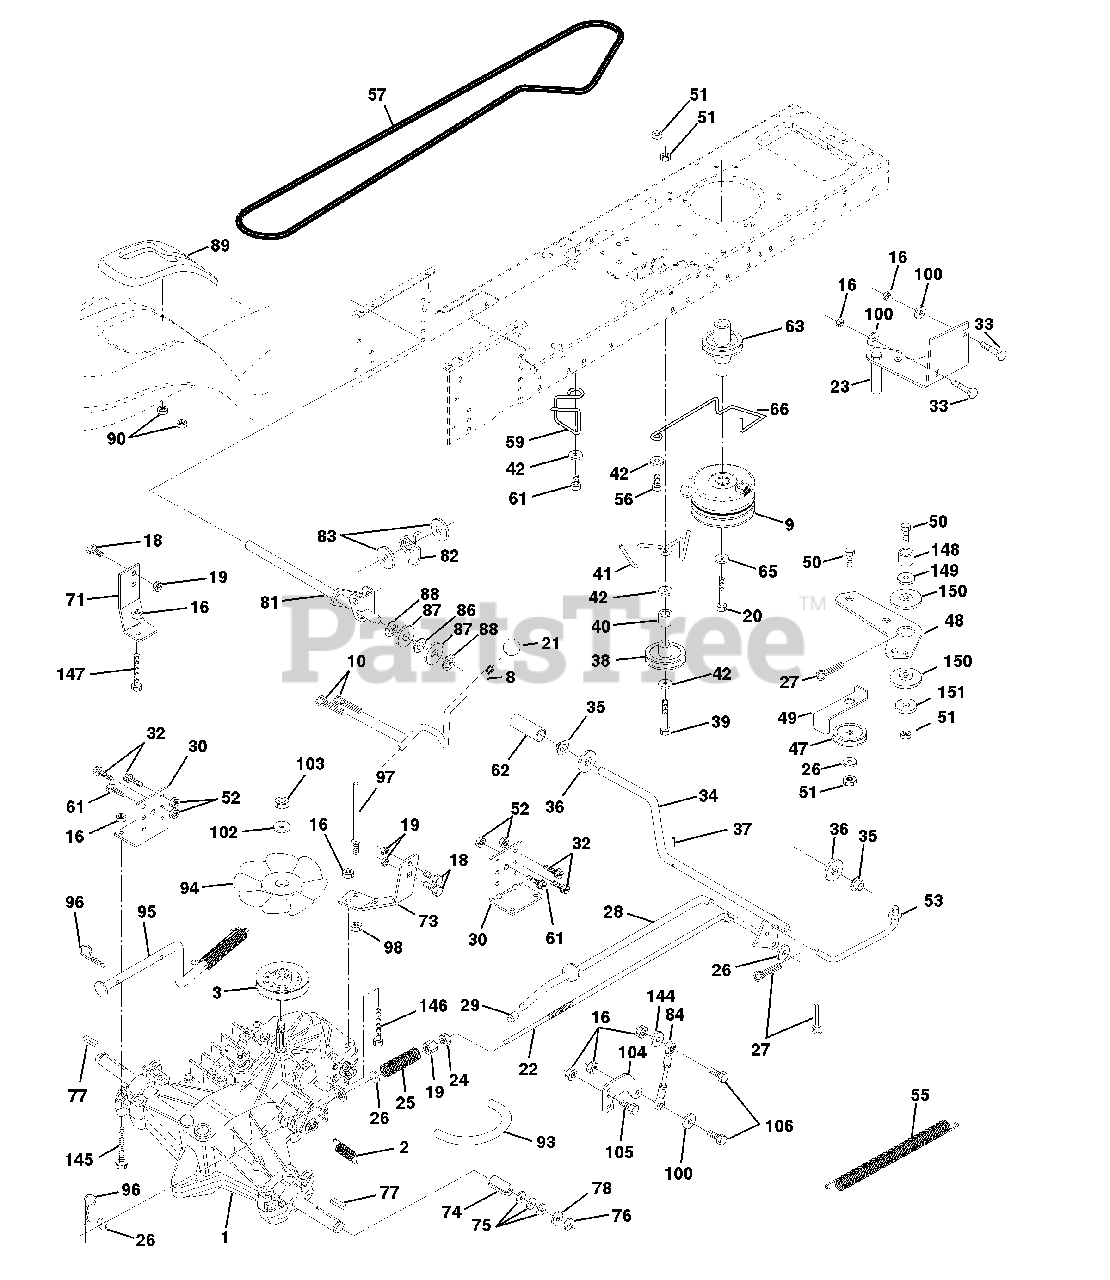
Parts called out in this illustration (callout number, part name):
1	Transaxle w/cas Hydro 319-0650
2	Spring, Return, Brake
3	Pulley, Transaxle Hydro 750 LT
8	Rod Shift STLT
9	Clutch Electric
10	Pin Cotter 1/8 x 1 CAD
16	Nut Lock Hex W/Ins. 5/16-18 Unc P
18	Bolt Fin Hex 3/8-16 Unc x 1 Gr.5
19	Nut Lock Hex W/Ins 3/8-16 Unc
20	Bolt, Hex 7/16-20 x 4-1/4 Ga. 5
21	Knob Deluxe 1/2-13 UNC BLK/BLK
22	Rod, Brake Hydro
23	Bracket Asm Mtg CL
24	Nut Hex Jam 3/8-16 UNC
25	Spring, Brake Rod
26	Washer
27	Pin Cotter 1/8 x 3/4 CAD.
28	Rod, Parking Brake
29	Cap, Parking Brake
30	Bracket, Transaxle
32	Bolt Hex Hd 5/16-18 Unc x 3/4
33	Bolt Carriage 5/16-18 UNC x 3/4
34	Shaft, Foot Pedal
35	Bearing, Nylon
36	Washer
37	Pin, Roll
38	Pulley, Idler, Flat
40	Spacer Split
41	Keeper, Belt Idler
42	Washer 13/32 x 13/16 x 12 Ga
47	Pulley, Idler, V-Groove Plastic
48	Bellcrank Clutch Grnd Drv Stl
49	Retainer, Belt Style Spring
50	Bolt
52	Nut Crown Lock 5/16-18
53	Link, Clutch
55	Spring, Return, Clutch
56	Bolt, Fin Hex 3/8-16 UNC x 1 1/4
57	V-Belt, Ground Drive
59	Keeper, Center Span
61	Screw Thdrol. 3/8-16 x 3/4 Ty. TT
62	Cover, Pedal Premium
63	Pulley, Engine
65	Washer Lock Hvy HLCL Spr 7/16
66	Keeper Belt Engine
71	Strap Torque Lh Hydro 18/20" T
73	Strap Torque Rh Hydro 0650
74	Spacer, Split
75	Washer 25/32 x 1-1/4 x 16 Ga.
77	Key, Square
78	Washer 25/32 x 1-5/8 x 16 Ga
81	Shaft Asm. Cross Hydro 20" Tires
82	Spring Torsion T/A
83	Washer 17/32 x 3/4 x 16 Ga.
84	Rod, Tie Hydro 20" Tires SPH Ball 4.75
87	Washer 21/32 x 1-1/4 x 16 Ga.
88	Ring Klip #5304-62
89	Console, Hydro
90	Nut Self-Thd Wsh-Hd 1/4 Zinc
93	Line Fuel Hydro 4"
94	Fan, Hydro 7"
95	Control Asm. Bypass Hydro
96	Retainer Spring 1" Zinc/Cad
97	Keeper Belt Rh Hydro 0750.18/20"
98	Nut Keps Hex 3/8-16 Unc
100	Washer 11/32 x 3/4 x 16 Ga.
102	Washer Belleville .501D x 1.50D
103	Nut Hex Jam Toplock 1/4-20 Unf
104	Arm, Control Hydro
105	Screw Cap Hex 5/16 x 18 x 1
106	Bolt Fin Hex 5/16-18 Unc x 1-1/4
144	Washer 11/32 x 5/8 x 16 Ga.
145	Bolt Hex 5/16-18 Gr. 5
146	Bolt Hex Flghd 5/16-18 x 2-1/4
147	Bolt Hex Flghd 5/16-18 x 1-1/2
149	Spacer Retainer PM Mower
150	Bushing Nylon Collered
151	Washer 13/32 x 2 x 10 Ga.
